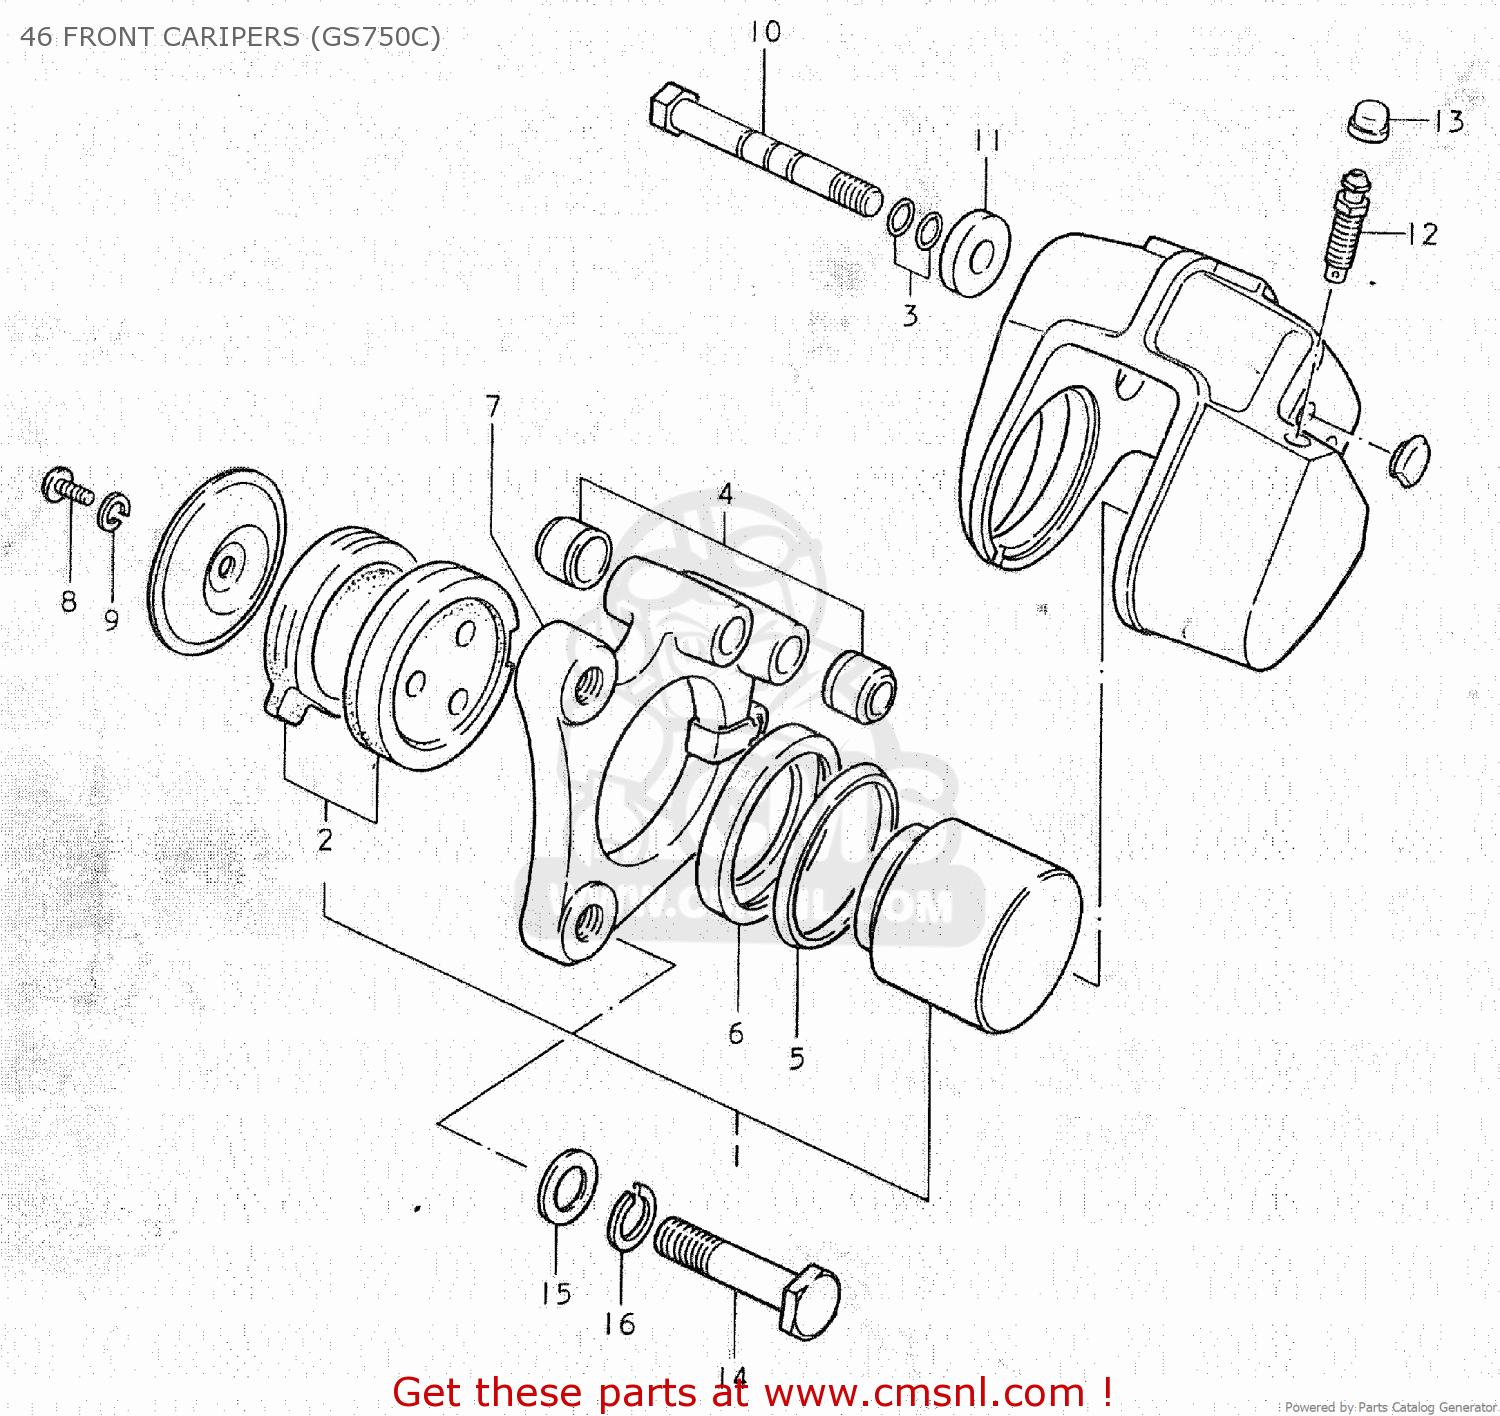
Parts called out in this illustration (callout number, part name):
1	PISTON SET
2	59302-45830 (MCA)
3	O RING
4	COVER,AXLE DUST
5	SEAL,FR CALIPE
6	BOOT,PISTON
7	HOLDER,CALIPERS
8	SCREW 6X12
9	LOCK WASHER
10	AXLE,CALIPER
11	WASHER,AXLE
12	BLEEDER
13	CAP,BREATHER
14	BOLT
15	WASHER
16	LOCK WASHER
